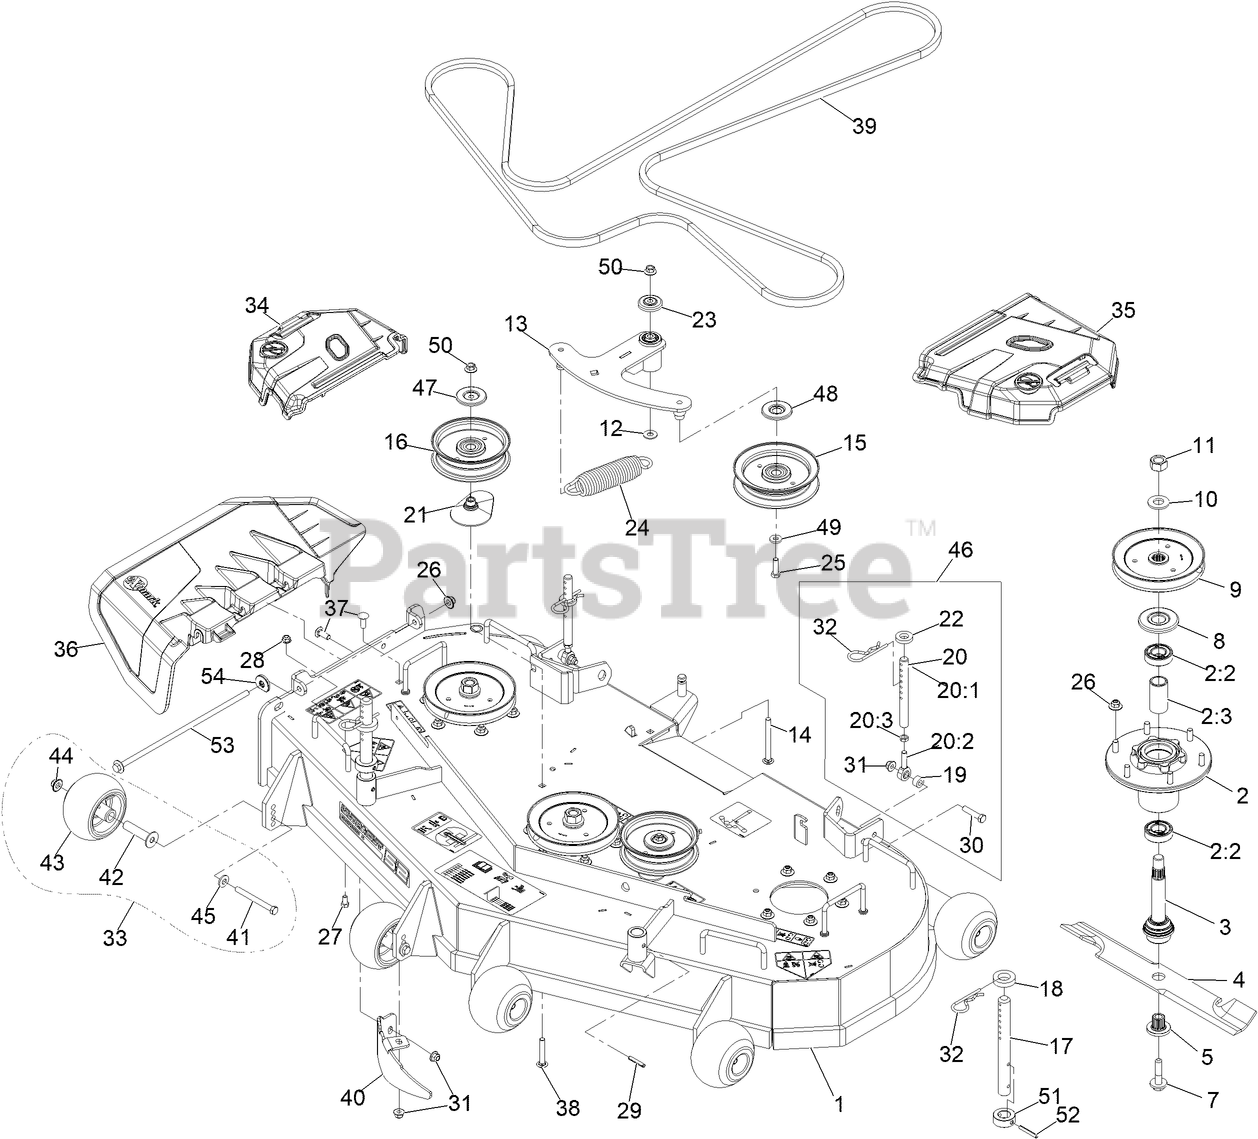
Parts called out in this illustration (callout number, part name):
1	ASM, DECK W/ DECALS, 52
2	ASM-CUTTER HSG WITH BEARINGS
2:2	BEARING-BALL
2:3	SPACER-BEARING
3	ASM-SPINDLE AND SEAL
5	BUSHING,SPLINED
7	SCREW,SEMS 1/2-20 X 2.19
8	GUARD,BEARING TOP .989
9	SHEAVE,BLADE DRIVE 6.50
11	NUT-HEX
12	WASHER-FLAT
13	ASM, DECK IDLER
14	SCREW-CARR
15	IDLER-PULLEY, FLAT
16	IDLER-PULLEY, FLAT 5.00X1.31
17	ROD, DECK SUPPORT
18	SPACER-DECK SUPPORT
20:1	LINK,SUPPORT
20:2	BALLJOINT
20:3	NUT-HJ
21	SPACER-PULLEY
23	GUARD-TOP
24	SPRING-EXTENSION
25	SCREW-HH
26	Nut-Nyloc 3/8-16 Flg
27	SCREW-HH
28	NUT-HF, NI
30	SCREW-HH
31	NUT-HF, NI
32	PIN,HAIR COTTER
33	KIT, ANTI-SCALP ROLLER
34	SHIELD, RT
35	SHIELD, LT
36	Chute-Deck Discharge
37	SCREW-CARR
38	BOLT-CARR, SHORT NECK
39	BELT, DECK DRIVE
40	BAFFLE-DOGLEG, LZ-VT52
41	SCREW-HH 3/8-16 X 3 3/4 GR 8
42	AXLE, ROLLER
43	ROLLER-SCALP, ANTI
44	Nut-Nyloc 3/8-16 Flg
45	WASHER-BELLEVILLE
46	KIT,SUPPORT LINK W/PIN
47	SHIELD-DUST
48	SHIELD-GUARD, DUST
51	COLLAR, DECK HEIGHT PIN
52	PIN-ROLL
53	Pin, Chute
54	Retainer, Chute
55	Nut-Nyloc 3/8-16 Flg
